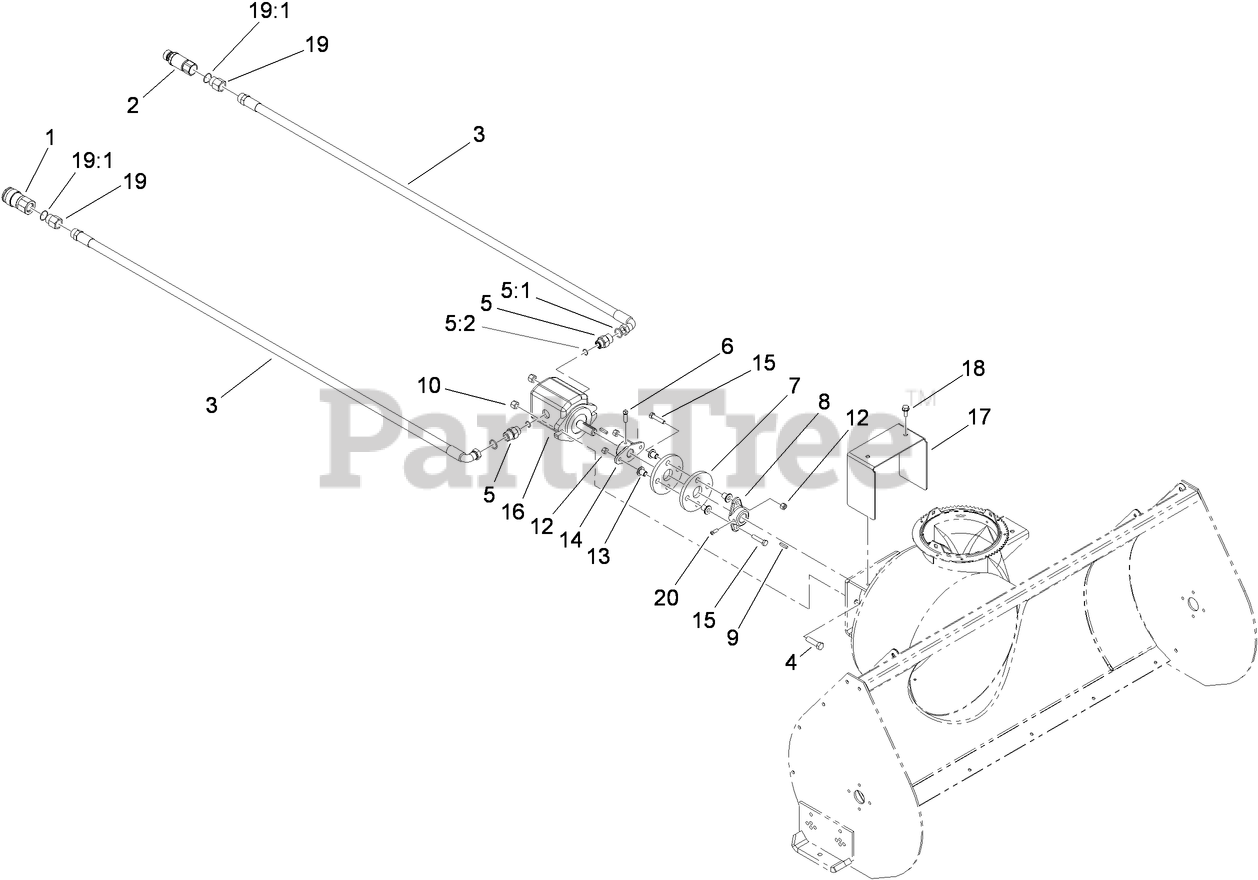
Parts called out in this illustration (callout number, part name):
1	COUPLER-FACE, FLUSH
2	NIPPLE-CONNECT, PRESSURE
3	HOSE-HYD
4	SCREW-HH
5	FITTING-STRAIGHT
5:1	O-RING
5:2	O-RING
6	SCREW-SET
7	COUPLING-RUBBER
8	HUB-PUMP
9	KEY
10	NUT-LOCK, NI
12	NUT-LOCK, NI
13	SPACER
14	HUB-PUMP
15	SCREW-HH
16	MOTOR-HYDRAULIC
17	SHIELD-MOTOR
18	SCREW-HWHTF
19	ADAPTER-HYD
19:1	O-RING
20	SCREW-SET, SQH
